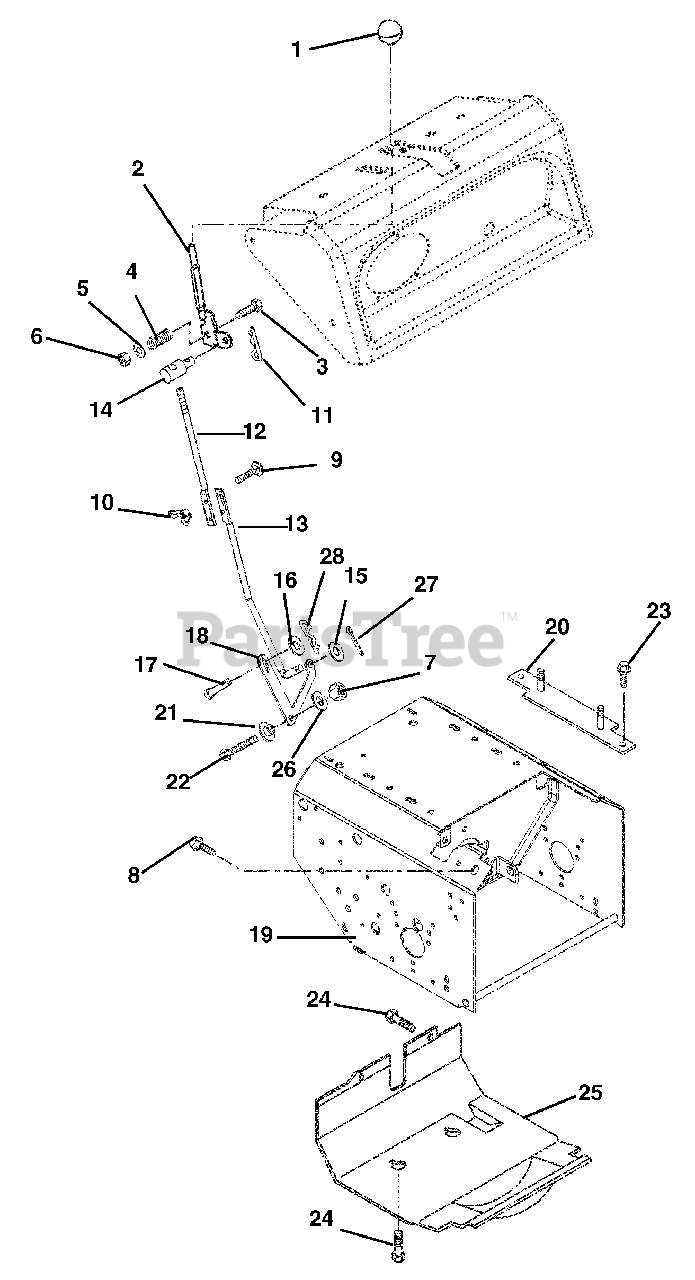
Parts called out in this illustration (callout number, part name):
1	KNOB,BALL -BLACK 1.47" .375-16
2	LEVER, SHIFT
3	@BLT-HEX .38-16X2.25 GR5 YWZC
4	SG-COMP .125X.781X1.250
5	@WSHR-FL-STL.438X1.00X.083 YWZ
6	@NUT-LK-CTR .38-16 YWZC
7	@NUT-LK-CTR .31-18 YWZC
8	BLT-SERHFWH .38-16X.75 YWZC
9	@BLT-RDHDSQNK .25-20X1.00 G5YZ
10	NUT-LK WING .250-20 YWZC
11	PIN-HAIR INT .08X.18X1.18 YWZC
12	ROD, SHIFT-UPPER
13	ROD, SHIFT-LOWER
14	PIVOT, ROD (TRUNNION ) .50
15	@PIN-CTR .09X.75 EXTPRSQCT YWZ
16	WSHR-FL-STL .382X.812X.023YWZC
17	CLEVIS PIN
18	ARM, SHIFT
19	FRAME, MAIN-WELDMENT
20	BOLT STRAP
20	STRAP, BOLT
21	BSHG-FLG .325X.500X.327X.875
22	@BLT-HEX .31-18X1.00 GR5 YWZC
23	@SCR-TAP .25-20X.37 HWH YWZ TR
24	SCR-TAP .31-18X.375 HWH TR YZ
25	COVER, BOTTOM
26	WSHR-FL-STL .328X.875X.062YWZC
27	@WSHR-FL-STL.531X1.06X.095YWZC
28	PIN-HAIR, ENDRIES #25 YWZC
